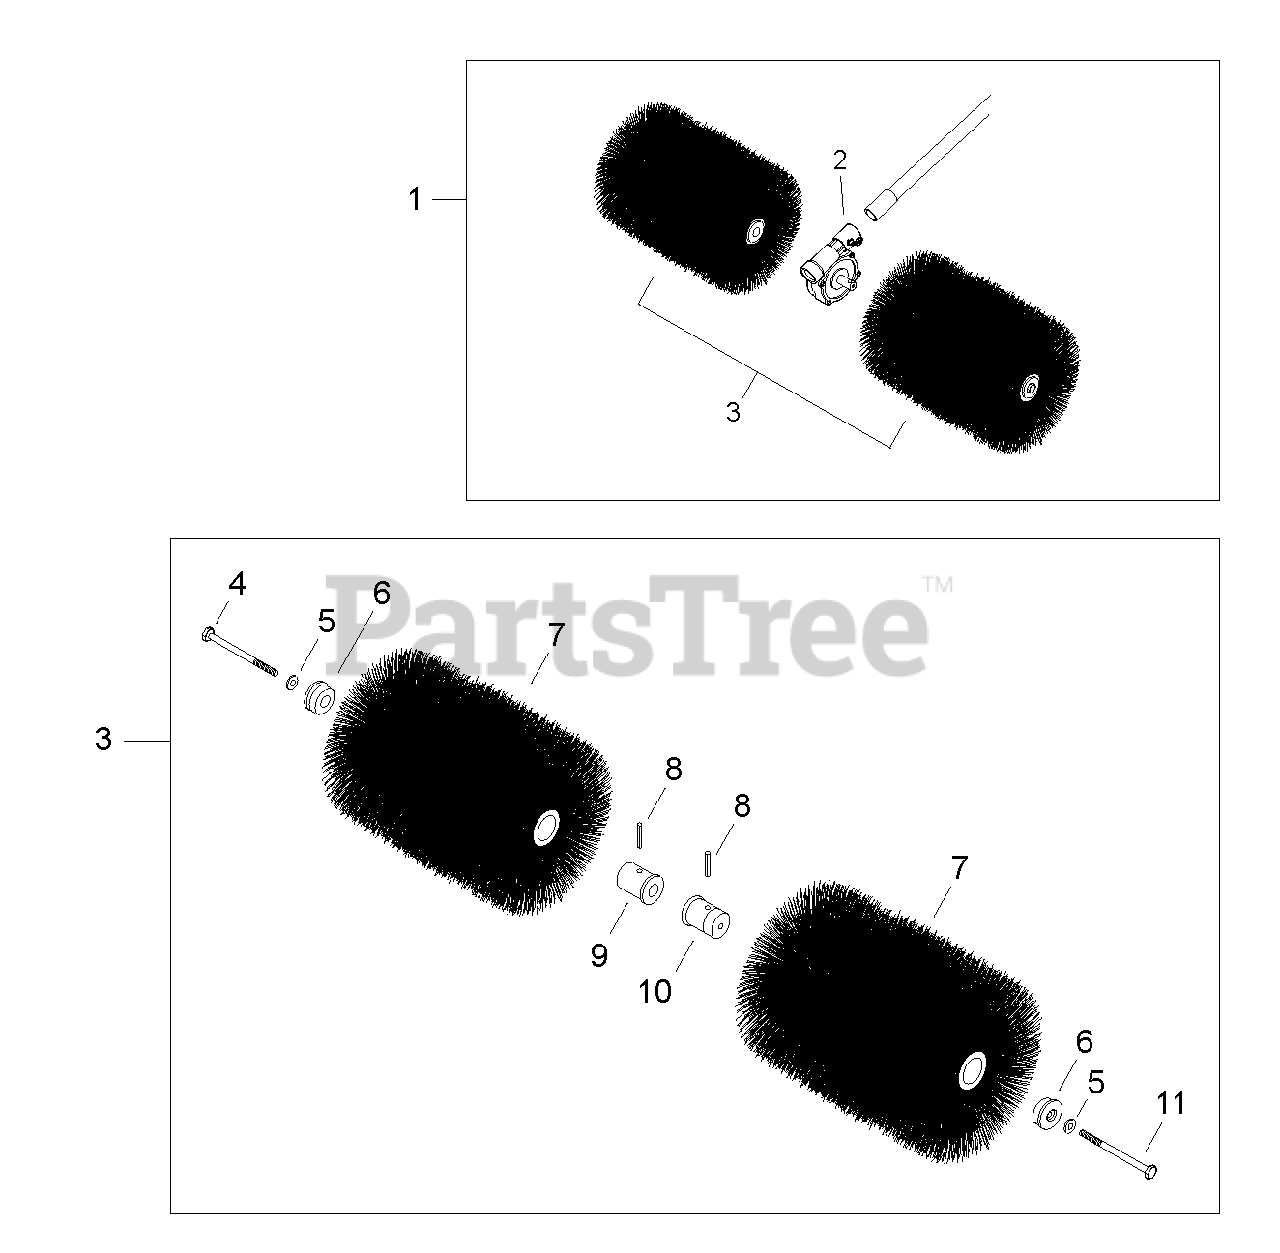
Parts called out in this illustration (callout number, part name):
1	BRUSH ASSY
2	GEAR CASE ASSY
3	BRUSH - ( + )
4	RIGHT HAND THREAD HEX - BLACK
5	WASHER
6	CAP
7	BRISTLE BRUSH
9	RIGHT HAND THREAD CORE
10	LEFT HAND THREAD CORE
11	RIGHT HAND THREAD HEX (SILVER)
